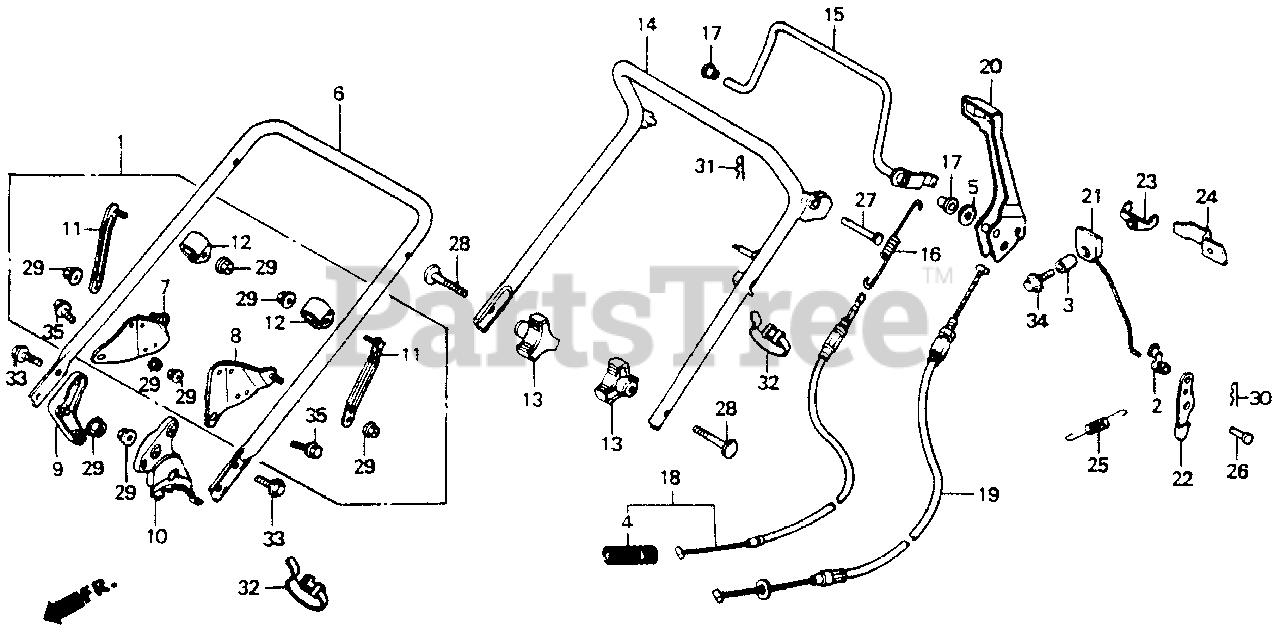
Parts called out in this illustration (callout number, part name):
1	SUPPORT KIT, HANDLE
2	JOINT, ROD
3	COLLAR, FAN
5	WASHER, EQUALIZER (NOT AVAILABLE)
6	PIPE, HANDLE (LOWER) *NH105* (MAT BLACK)
7	STAY, R. HANDLE SUPPORT
8	STAY, L. HANDLE SUPPORT
9	STAY, R. HANDLE *NH35M* (CLOUD SILVER METALLIC)
10	STAY, L. HANDLE *NH35M* (CLOUD SILVER METALLIC)
11	PLATE, HANDLE SUPPORT
12	HANGER, HANDLE SUPPORT
13	GRIP, HANDLE JOINT (UPPER)
14	PIPE, HANDLE (UPPER) *NH105* (MAT BLACK)
19	CABLE, ROTO-STOP
20	LEVER, ROTO-STOP
21	ROD, RATCHET PUSH
22	LEVER, LOCK
23	PLATE, PUSH ROD
25	SPRING, RATCHET RETURN
26	PIN, SEAT HINGE
27	PIN, CLUTCH LEVER
28	BOLT, HANDLE HOLDER
29	NUT, FLANGE (8MM)
30	PIN, LOCK (6MM)
31	PIN, LOCK (8MM)
32	TIE, CABLE
33	BOLT, FLANGE (8X14)
34	BOLT, FLANGE (6X10)
35	BOLT, FLANGE (8X18)
